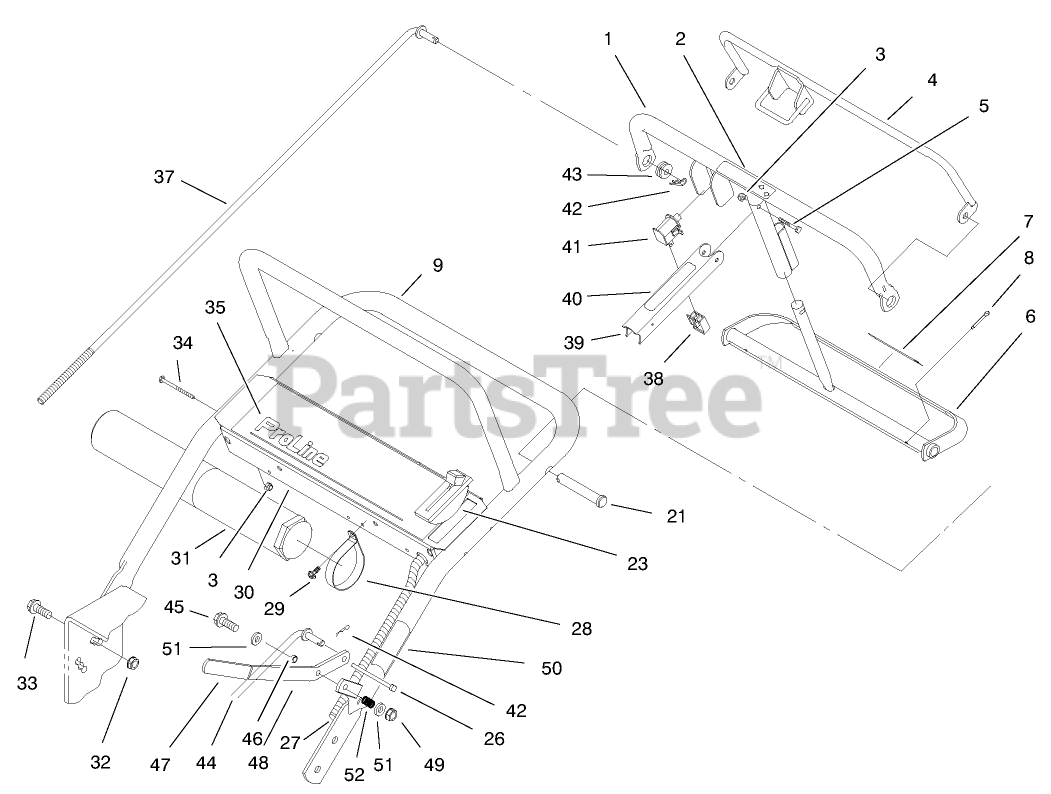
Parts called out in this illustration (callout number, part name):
1	Control Bar
2	DECAL
3	NUT-LOCK, NI
4	Bail ASM
5	SCREW-SHH
6	Control Pivot
7	DECAL
8	PIN-COTTER
9	Upper Handle ASM
21	PIN-CLEVIS
23	Throttle Control
26	TIE-CABLE
27	Wire Harness-Kawasaki
28	CLAMP-R
29	SCREW-HWHTF
30	Panel-Control
31	TUBE-MANUAL
32	NUT-HF
33	SCREW-HHF
34	SCREW-SHH
35	Decal-Panel
37	Rod-Control
38	CONNECTOR-BODY
39	Lever-Parking Brake
40	Decal-Parking Brake
41	SWITCH
42	PIN-COTTER
43	GROMMET-RUBBER
44	Linkage-Blade Drive
45	SCREW-HH
46	SPACER
47	Grip
48	Lever-Blade Engagement
49	NUT-HEX
50	Decal-Blade Engagement
51	WASHER-FLAT
52	Spring
